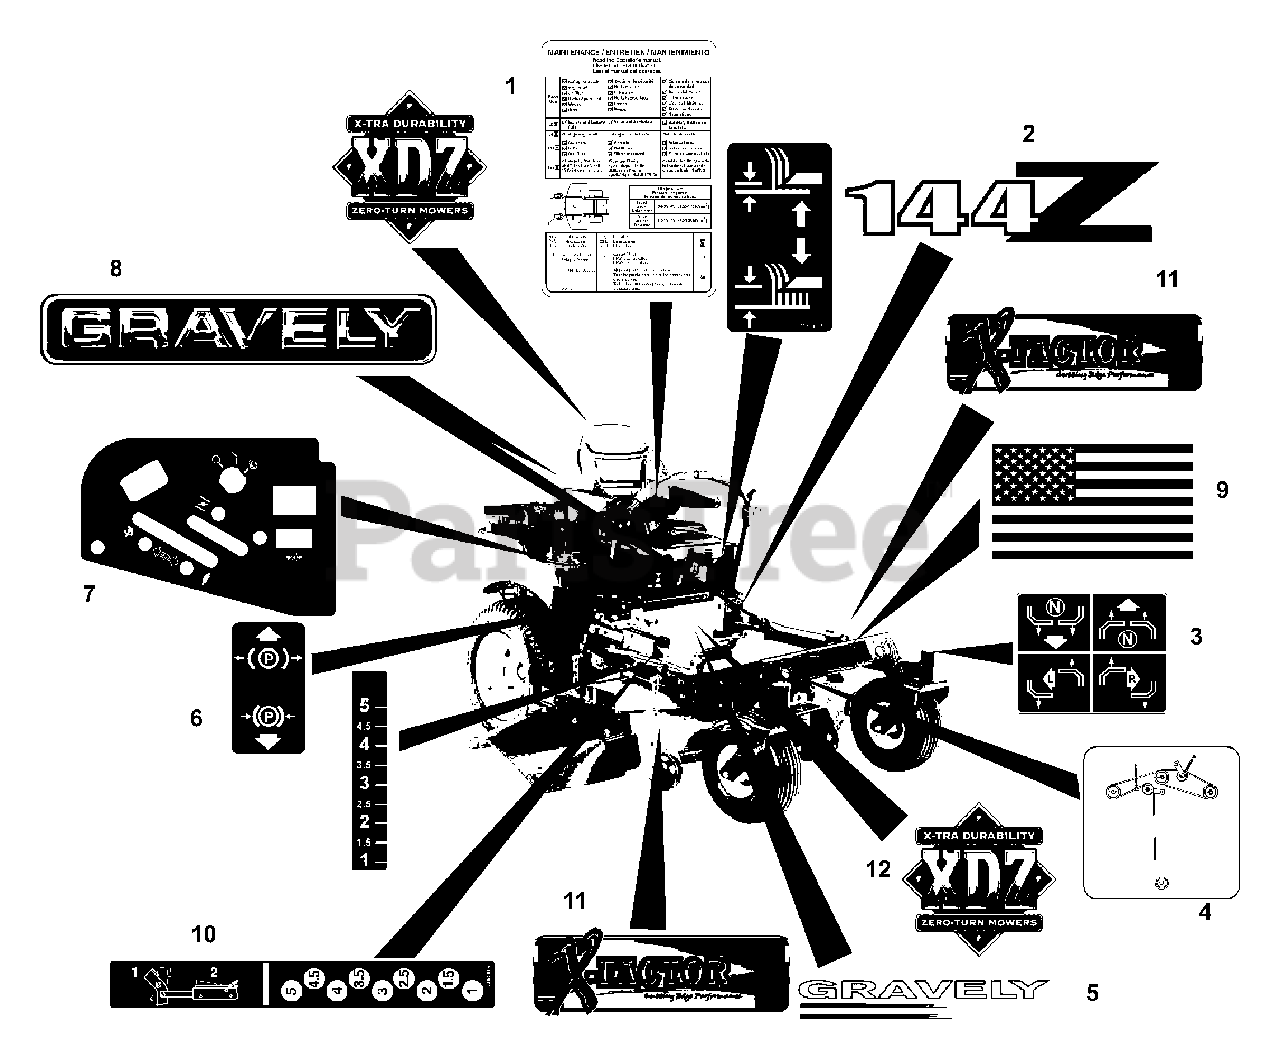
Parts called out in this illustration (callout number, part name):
1	Decal, Service Instructions
2	Decal, PM 152Z
3	Decal, Instructional Steering
4	Decal, Belt Diagram
5	Decal, ZT Hood
6	Decal, Parking Brake Lever
7	Decal, Control Panel
8	Decal, 15" Gravely Logo
9	Decal, American Flag
10	Decal, Height of Cut
11	Decal, X-Factor
12	Decal, Gravely 90th Anniversary
